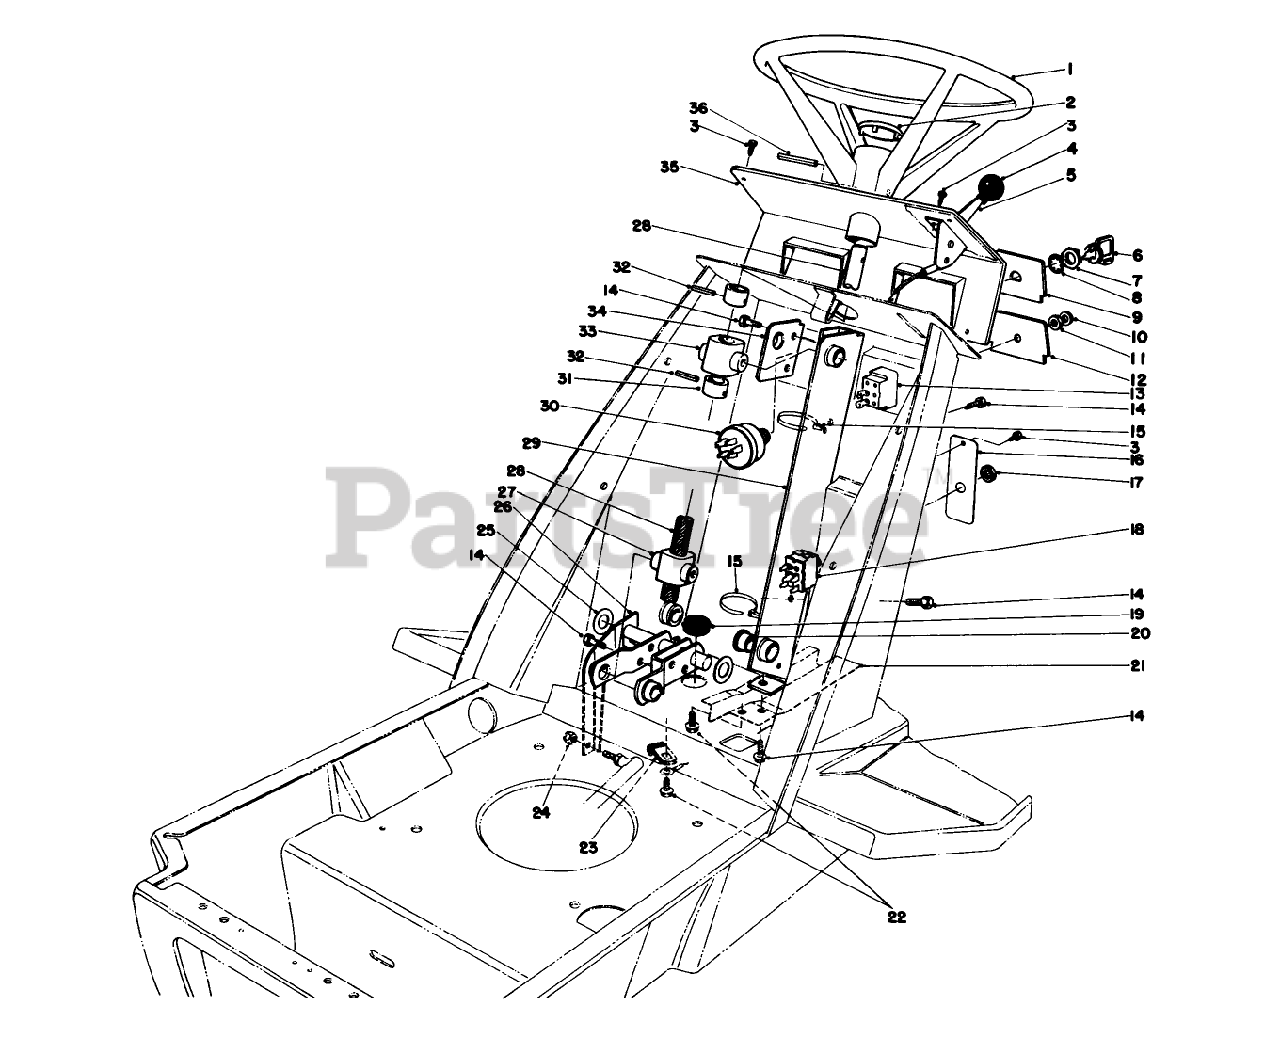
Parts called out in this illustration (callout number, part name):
1	STEERING WHEEL ASM
3	SCREW-HWHTF
4	KNOB-CONTROL
5	THROTTLE CONTROL
6	KEY-IGNITION
7	NUT-HH
8	WASHER-LOCK
11	NUT-LOCK
13	Light Switch (Incl. Ref. #10 11)
14	SCREW-THD ROLL, HWH
15	TIE-CABLE
19	GROMMET
20	BEARING-FLANGE
22	SCREW
23	CLIP-FUEL LINE
24	NUT-HEX
28	STEERING SHAFT
30	SWITCH-STARTER
31	STRG SHAFT COLLAR
32	PIN-SPRING
36	PIN-ROLL
